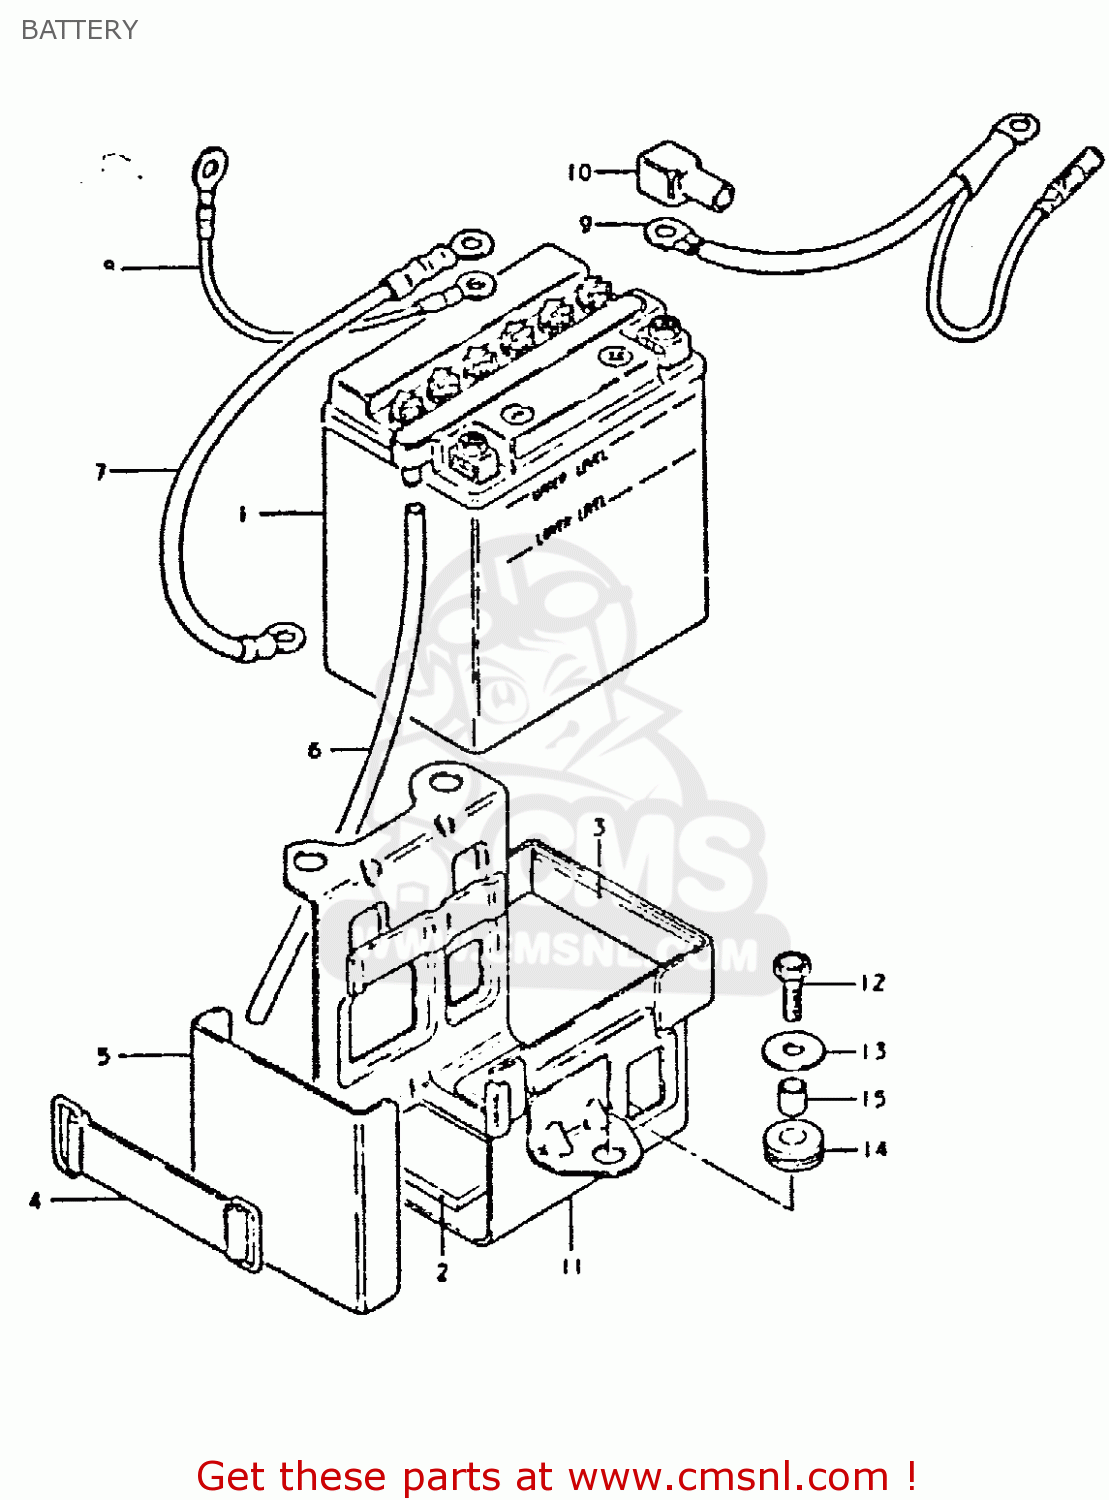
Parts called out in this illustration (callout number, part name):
1	BATTERY ASSY (12V)
2	CUSHION,BATTERY
3	PROTECTOR,20X9
4	BAND
5	COVER,BATTERY
6	HOSE,BATTERY EXHAUST
7	CORD,BATTERY MINUS
8	WIRE
9	WIRE,BATTERY PLUS
10	CAP,TERMINAL
11	HOLDER,BATTERY
12	BOLT
13	WASHER
14	CUSHION
15	SPACER (6.1X9X9)
